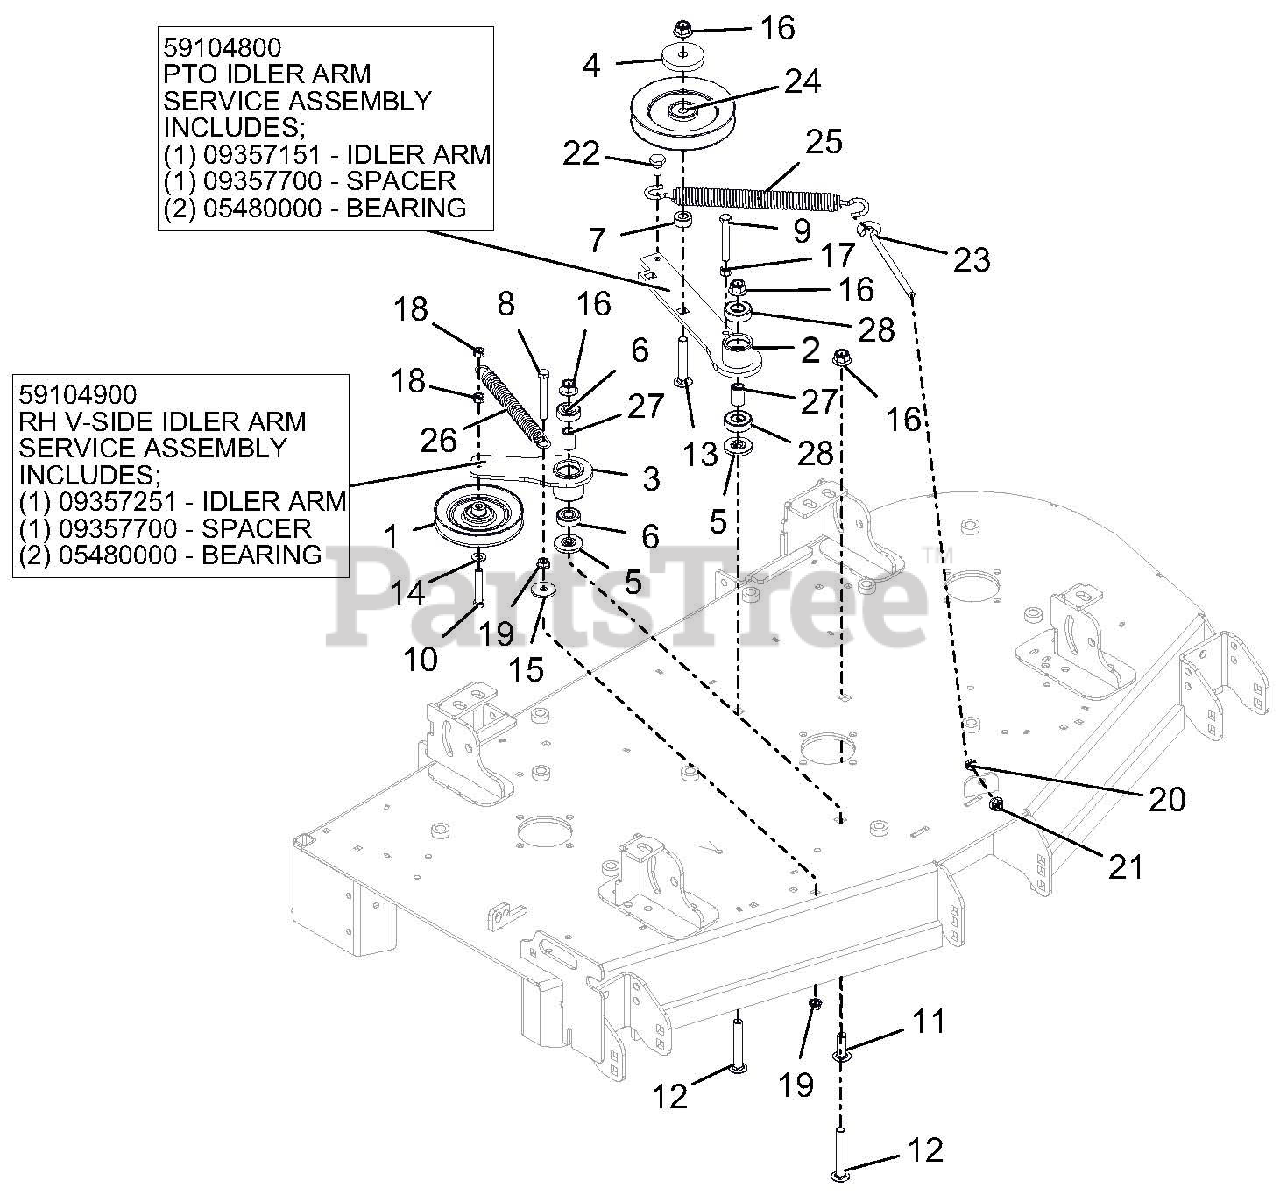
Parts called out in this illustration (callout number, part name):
1	IDLER, V-5.00"
2	DECK PTO IDLER ARM WMT - BLK
2	PTO IDLER ARM ASSEMBLY
2	SPACER .510 X .75 X 1.1485
2	BRG-BALL .50X1.38X.438 SEALED
3	DECK RH IDLER ARM WMT - BLK
3	RH V-SIDE IDLER ARM ASSEMBLY
3	SPACER .510 X .75 X 1.1485
3	BRG-BALL .50X1.38X.438 SEALED
4	CAP, IDLER BEARING SEALING
5	SPACER, IDLER ARM
6	BRG-BALL .500X1.38X.437
7	BSHG, SPCR .502X.997X.50 PM
8	@BLT-HEX .38-16X3.00 GR5 YWZC
9	@BLT-HEX .38-16X2.75 GR5 YWZC
10	@BLT-HEX .38-16X2.25 GR5 YWZC
11	BLT-RDHDSHSQNKFT.50-13X1.50 G5
12	BLT,RDHDSQSHNK.50-13X3.25 G5YZ
13	@BLT-RDHDSQNK .50-13X3.00 G5YZ
14	@WSHR-FL-STL.406X.812X.065 YWZ
15	WSHR-FL-STL .406X1.375X.135 YZ
16	@NUT-LK-NYL-FLG .50-13 YWZC
17	@NUT-HEX .38-16 YWZC
18	@NUT-LK-CTR .38-16 YWZC
19	@NUT-SPNLK-FLG .375-16 YWZC
20	NUT-HEX-JAM .375-16 YWZC
21	@NUT-LK-NYL-FLG .38-16 YWZC
22	BLT,SHLDR EP .38-16X.30 HEX YZ
23	BOLT, .38-16X6.00 .62 DIA EYE
24	SHV, .50"ID X 6.00"OD V-IDLER
25	SPRING, EXTENSION
26	SPRING, EXTENSION
27	SPACER .510 X .75 X 1.1485
28	BRG-BALL .500X1.38X.437 BOXED
